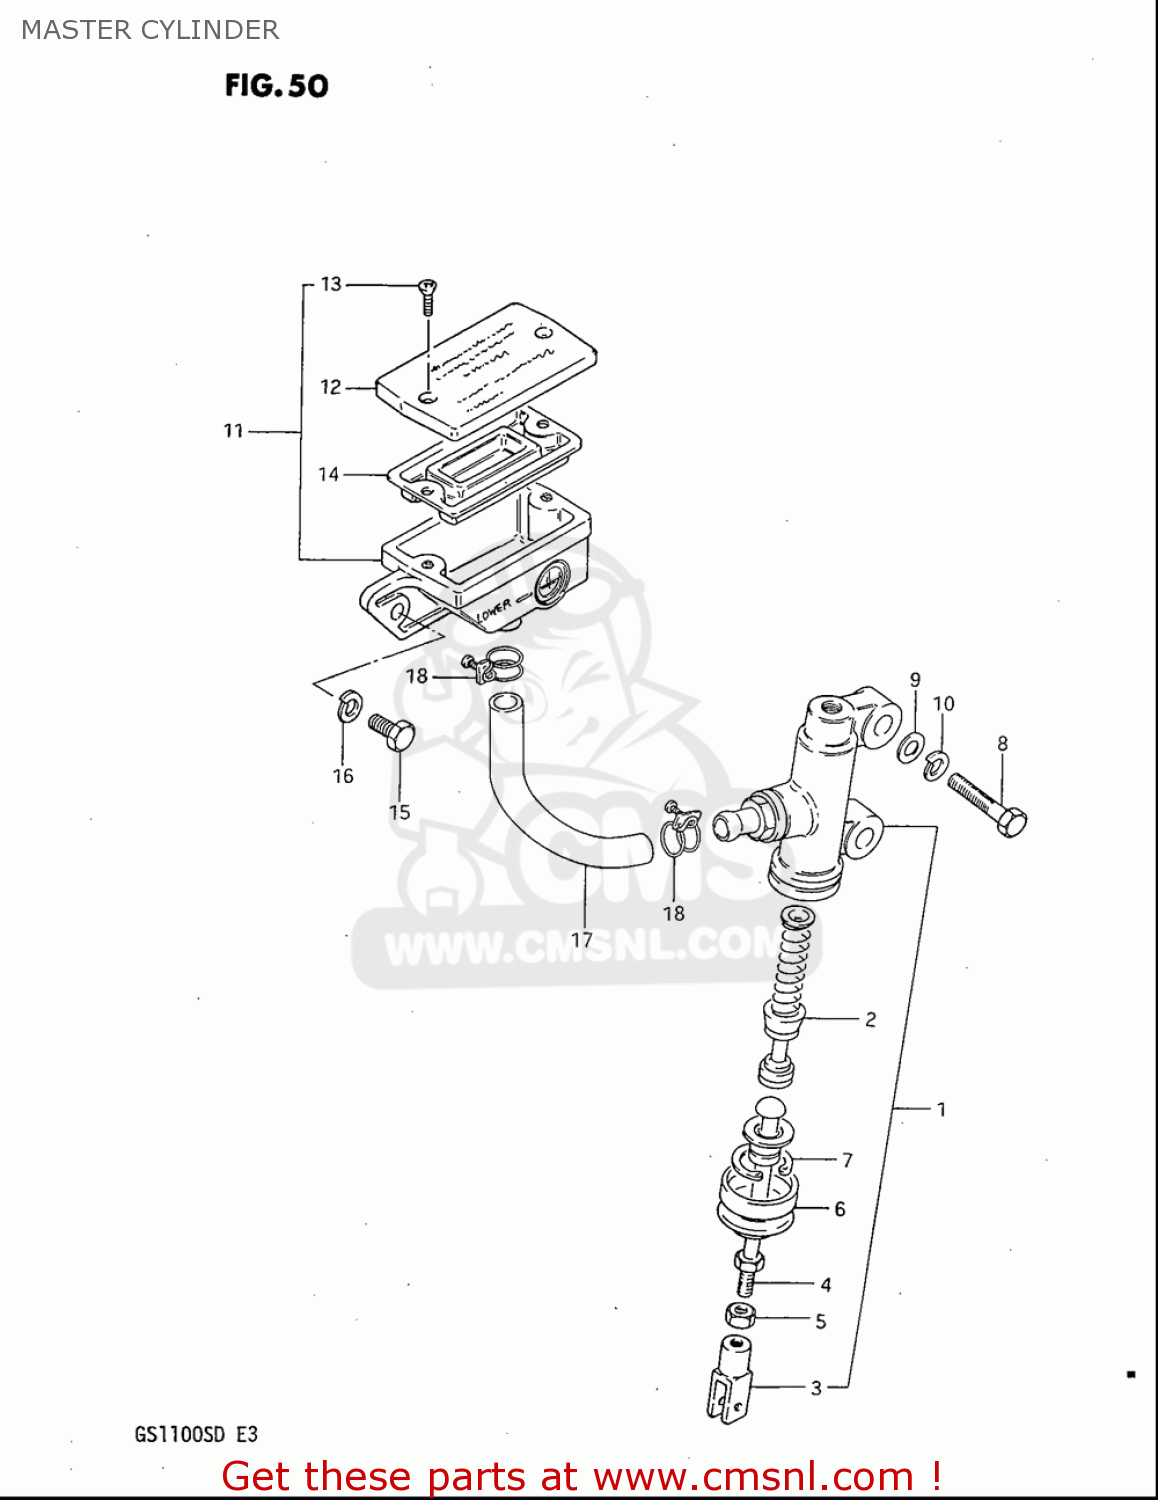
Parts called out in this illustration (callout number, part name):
1	CYLINDER ASSY,RR MASTER
2	PISTON/CUP SET
3	YOKE
4	LOD,PUSH
5	NUT,MASTER CYLINDER
6	BOOT
7	CIRCLIP
8	BOLT
9	WASHER
10	WASHER,LOCK
12	CAP
13	SCREW
14	15
15	BOLT
16	WASHER,LOCK
17	HOSE,RESERVOIR TANK
18	CLAMP
